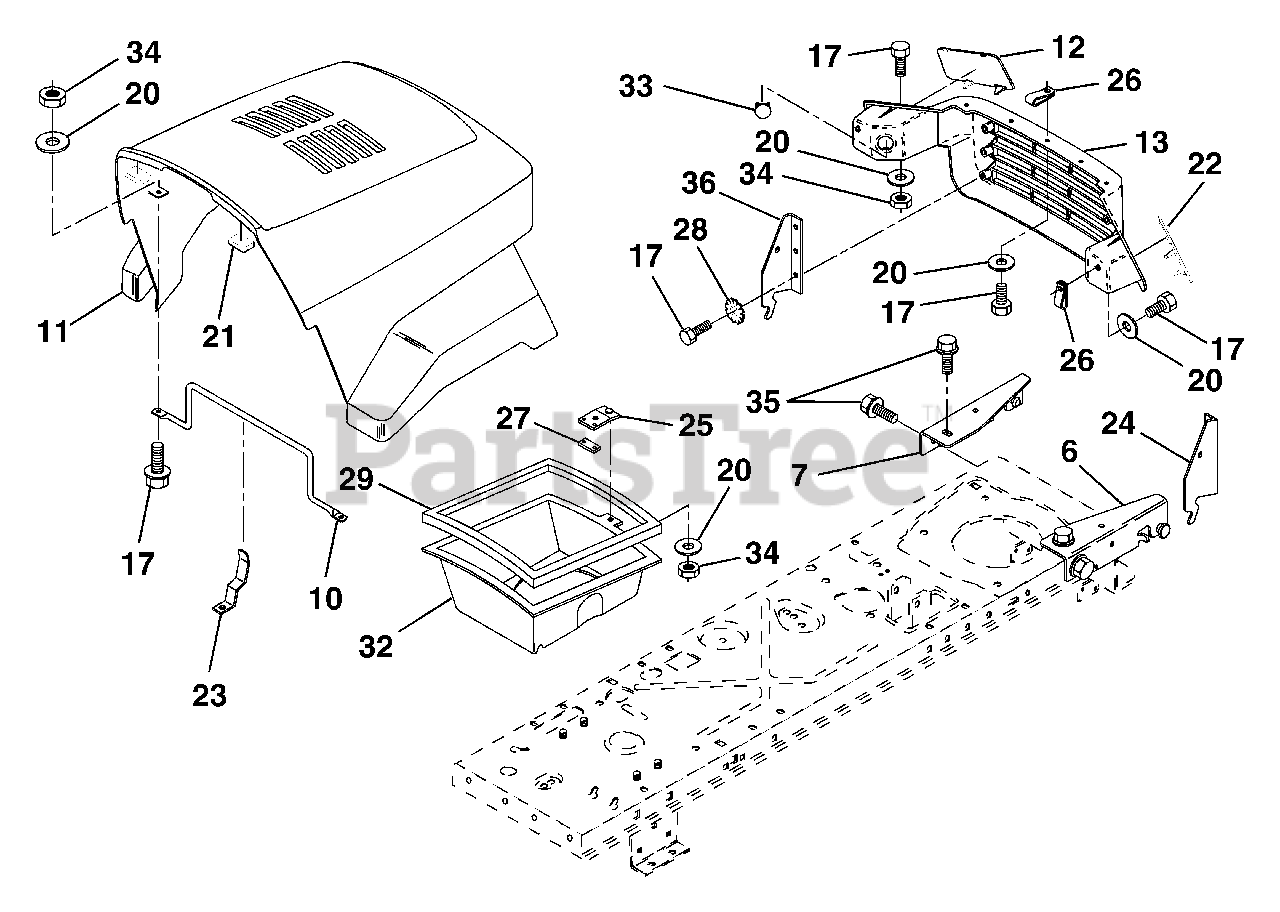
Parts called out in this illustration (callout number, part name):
6	Bracket Asm., Pivot Hood RH
7	Bracket Asm., Pivot Hood LH
10	Brace, Hood
13	Grille
17	Bolt, Fin Hex 1/4-20 x 5/8
20	Washer, Flat 1/4
21	Bumper, Hood
23	Latch, Hood
24	Bracket, Pivot Hood RH
25	Clip, Asm. Duct Air
26	Clip, Tinnerman
27	Clip, Tinnerman
28	Washer, Lock Ext. Tooth
29	Strip, Foam
32	Duct, Air Hood
33	Plug, Socket Light
34	Nut, Fin Hex 1/4-20
35	Screw, Thdrol 5/16-28 x 3/4
36	Bracket, Pivot Hood LH
